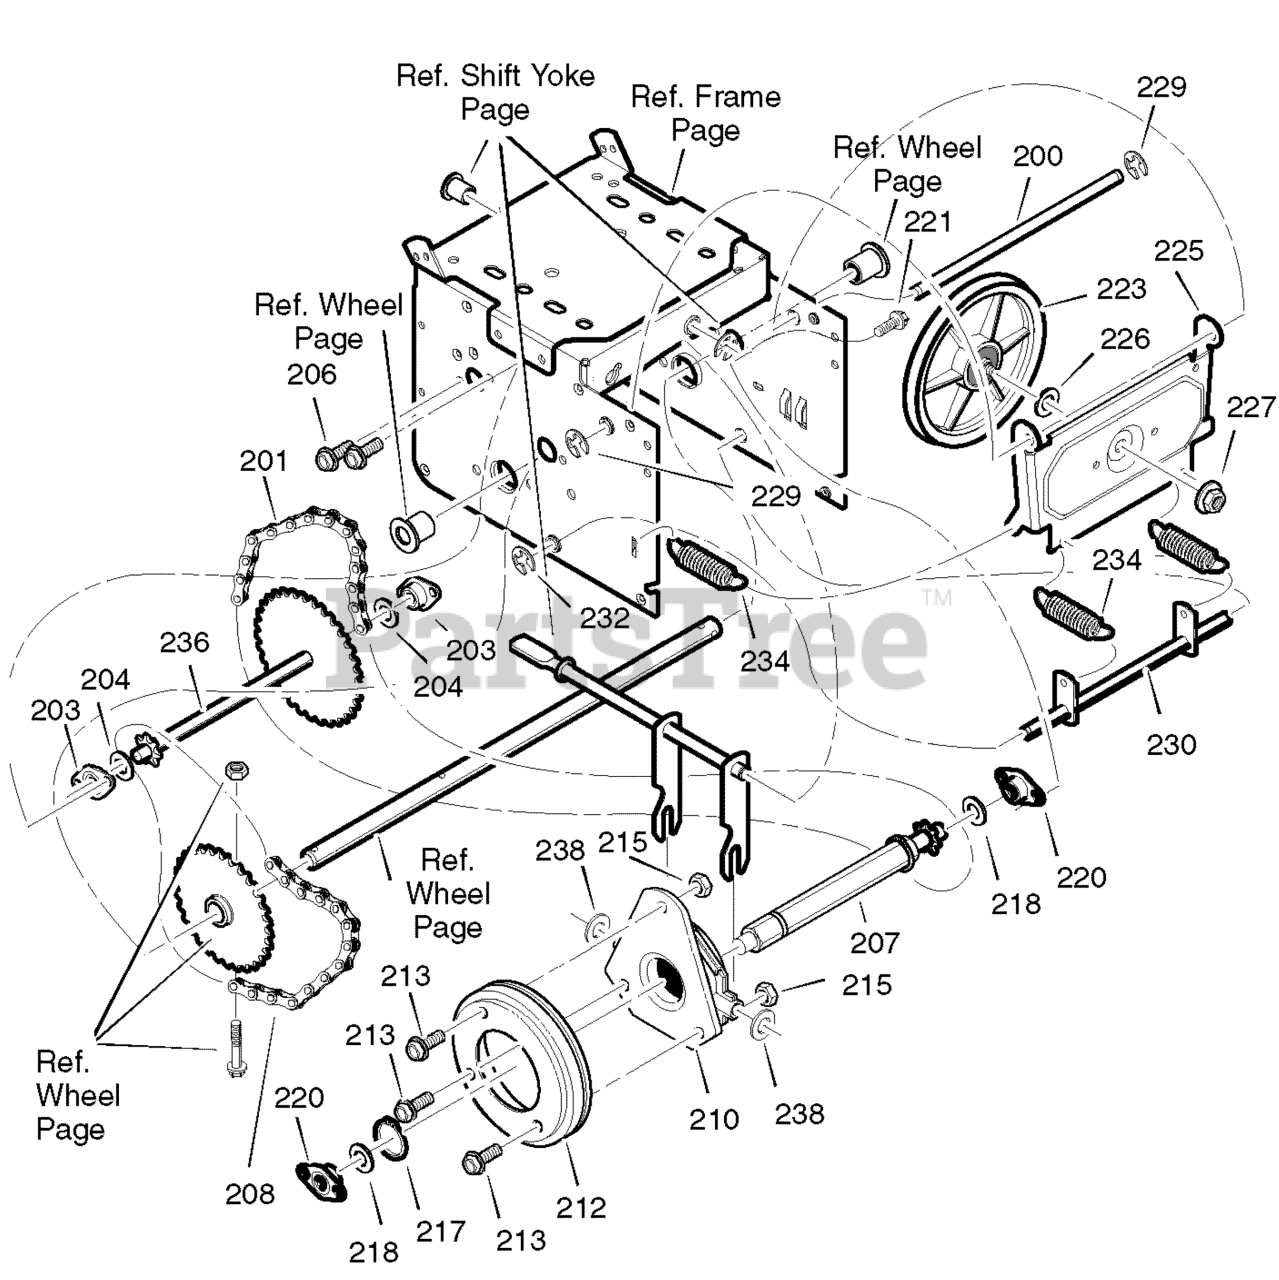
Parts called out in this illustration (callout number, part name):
200	LF AXLE, SWING PLATE YZ
201	CHAIN, ROLLER #42x19.00
203	BEARING AND RETAINER, ASSY
204	WASHER
206	SCREW, TAP 5/16-18x0.5
207	ASSY, HEX SHAFT
208	CHAIN, ROLLER #36x18.00 LG
210	BEARING, TRUNION CLUTCH R
212	WHEEL, FRICTION DISC
213	SCREW, 1/4-20 x 0.63
215	NUT, KEPS HEX 1/4-20
217	RING, RETEXT
218	WASHER
220	BEARING AND RETAINER, ASSY
221	SCREW, TAP 5/16-18 x .5
223	ASSY, FRICTION PULLEY
225	LF PLATE, SWINGING YZ
226	SPACER, FRICTION PULLEY
227	NUT, FLANGE LOCK 3/8-24
229	RETAINER, RING
230	LF ASSY, SPRING LINK YZ
232	RETAINER, RING
234	SPRING, EXTENSION
236	WLD, INTERMED SPROCKET 33T/7
238	WASHER, FLAT
